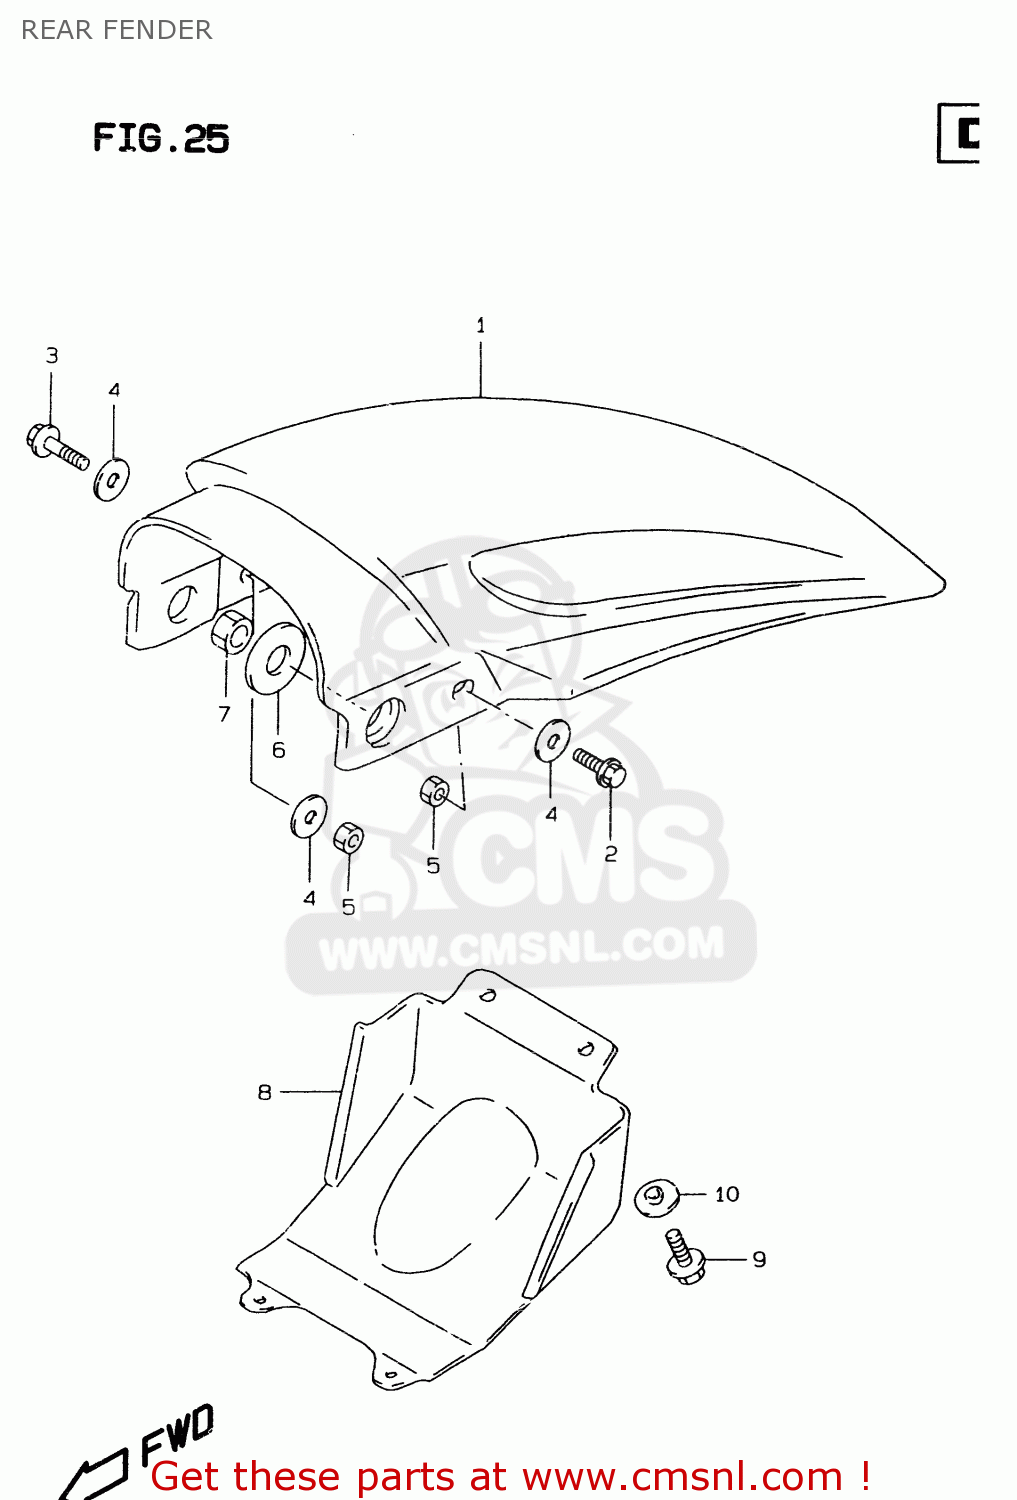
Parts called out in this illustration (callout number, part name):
1	FENDER,RR
2	BOLT
3	BOLT,G/S SWITC
4	WASHER(6.5X20X1.6)
5	NUT 6MM
6	WASHER(10.5X30X2.3)
7	NUT
8	MUDGUARD,RR FENDER FR
9	BOLT
10	WASHER
